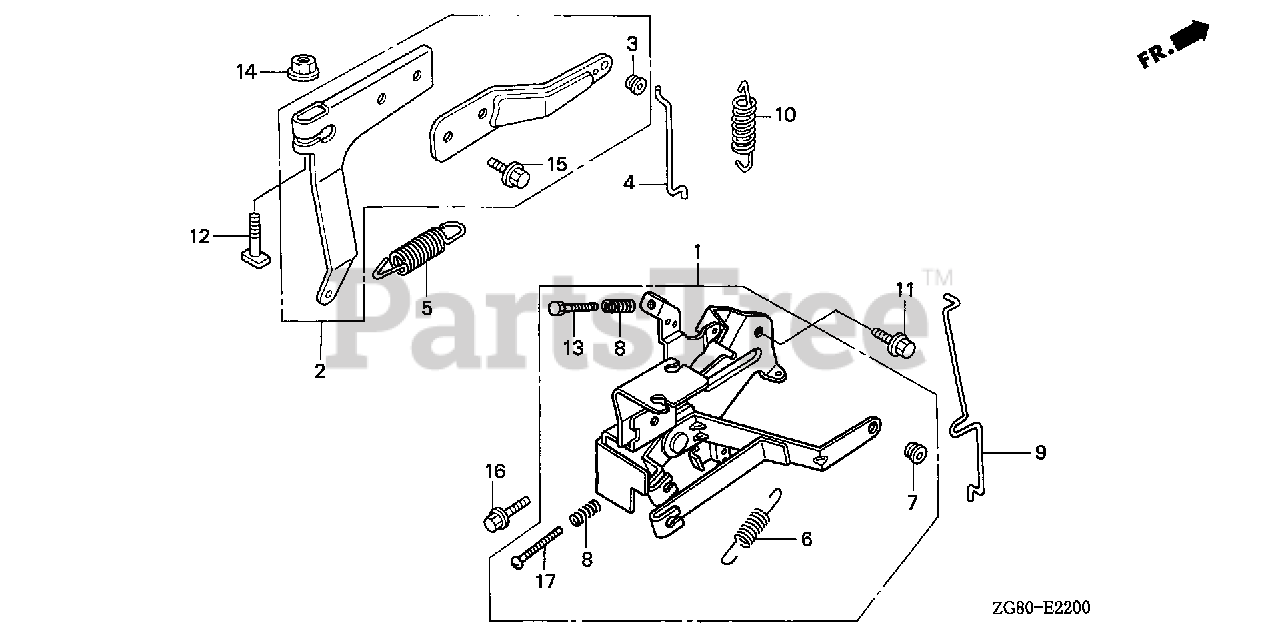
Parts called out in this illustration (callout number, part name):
2	ARM, GOVERNOR
3	COLLAR, LEVER
4	ROD, GOVERNOR
5	SPRING, GOVERNOR (H=57)
6	SPRING, CONTROL LEVER RETURN
7	COLLAR, LEVER
8	SPRING, CONTROL ADJUSTING
9	ROD, CHOKE
10	SPRING, THROTTLE RETURN
11	BOLT, FLANGE (6X14) (CT200)
12	BOLT, GOVERNOR ARM
13	BOLT, RECESSED (5X34)
14	NUT, FLANGE (6MM)
15	BOLT, FLANGE (6X8)
16	BOLT, FLANGE (8X14)
